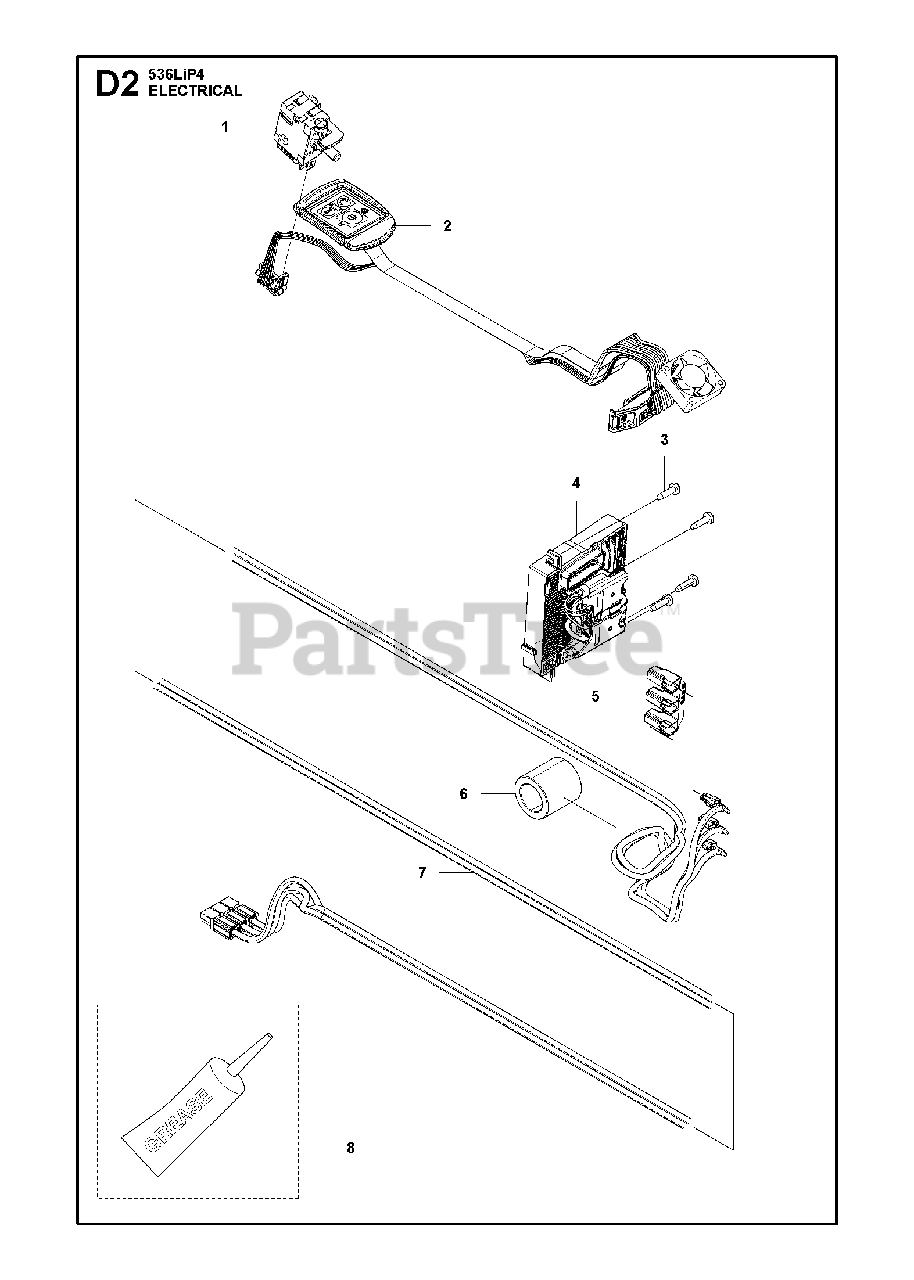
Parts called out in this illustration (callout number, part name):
1	TRIGGER SWITCH
2	WIRING ASSY POLE SAW
4	CONTROL UNIT
5	HOUSING POWER TIMER 3
6	FERRITE CORE
7	Wiring Assembly, Motor Cable Poles
8	GREASE TUBE Q8 RUYSDAEL WR2
